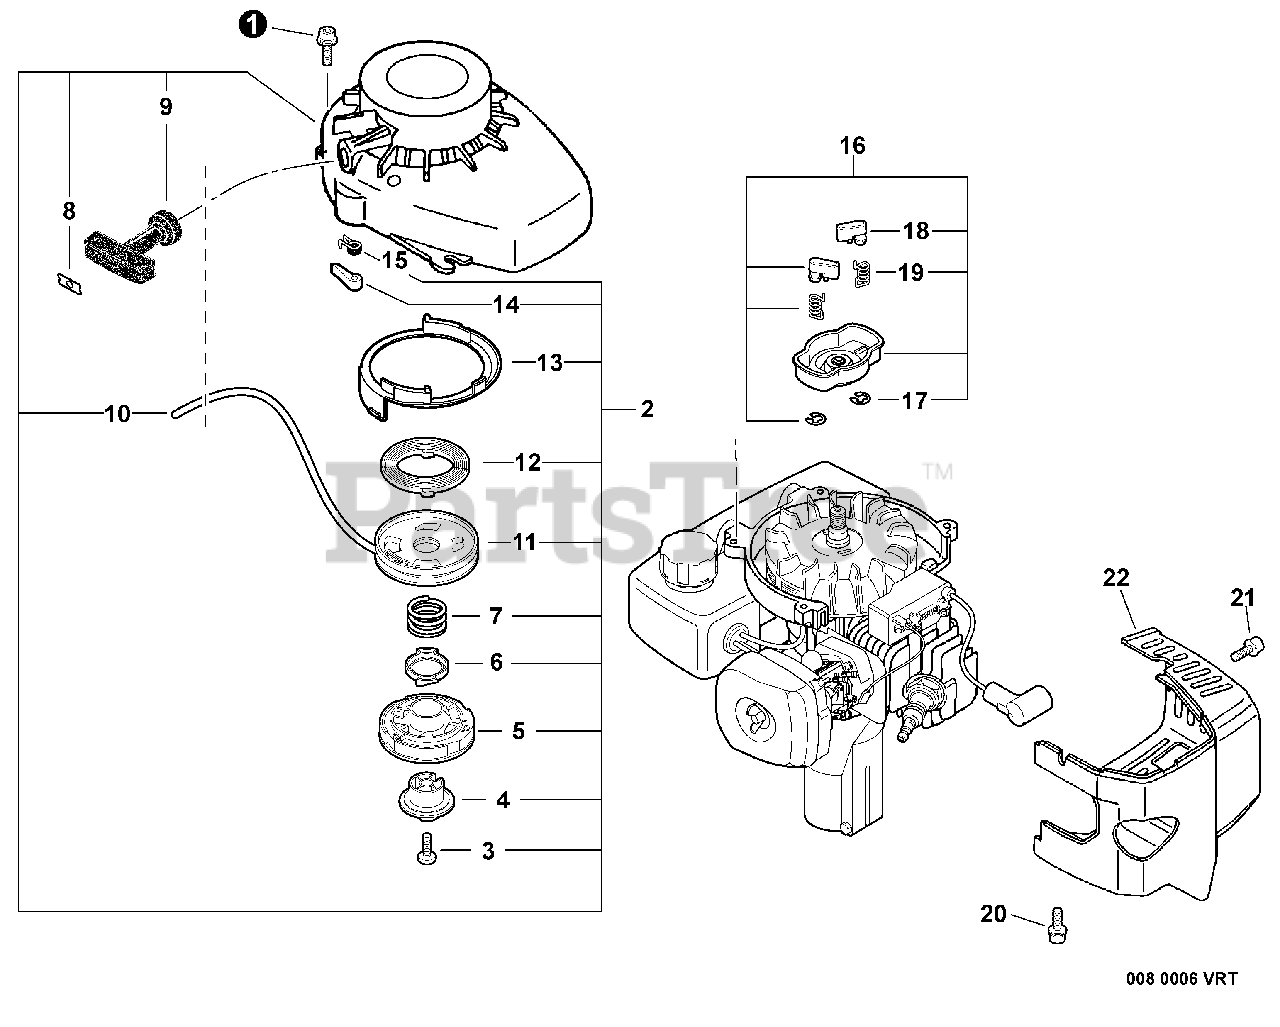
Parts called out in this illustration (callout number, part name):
1	SCREW - 4X16
2	STARTER ASSY - GRAY
4	PLATE, CAM
5	SPRING ASSY
7	SPRING, RETURN
8	RETAINER, ROPE
9	GRIP, STARTER
10	ROPE, STARTER - 3X800
11	REEL, ROPE
12	SPRING, REWIND
13	CASE, STARTER
14	PAWL, STARTER
15	SPRING, PAWL RETURN
16	STARTER PAWL ASSY
17	RING, RETAINING - 4
18	PAWL, STARTER
19	SPRING, RETURN
20	SCREW - 4X8
21	SCREW - 4X18
30	COVER, ENGINE - GRAY
